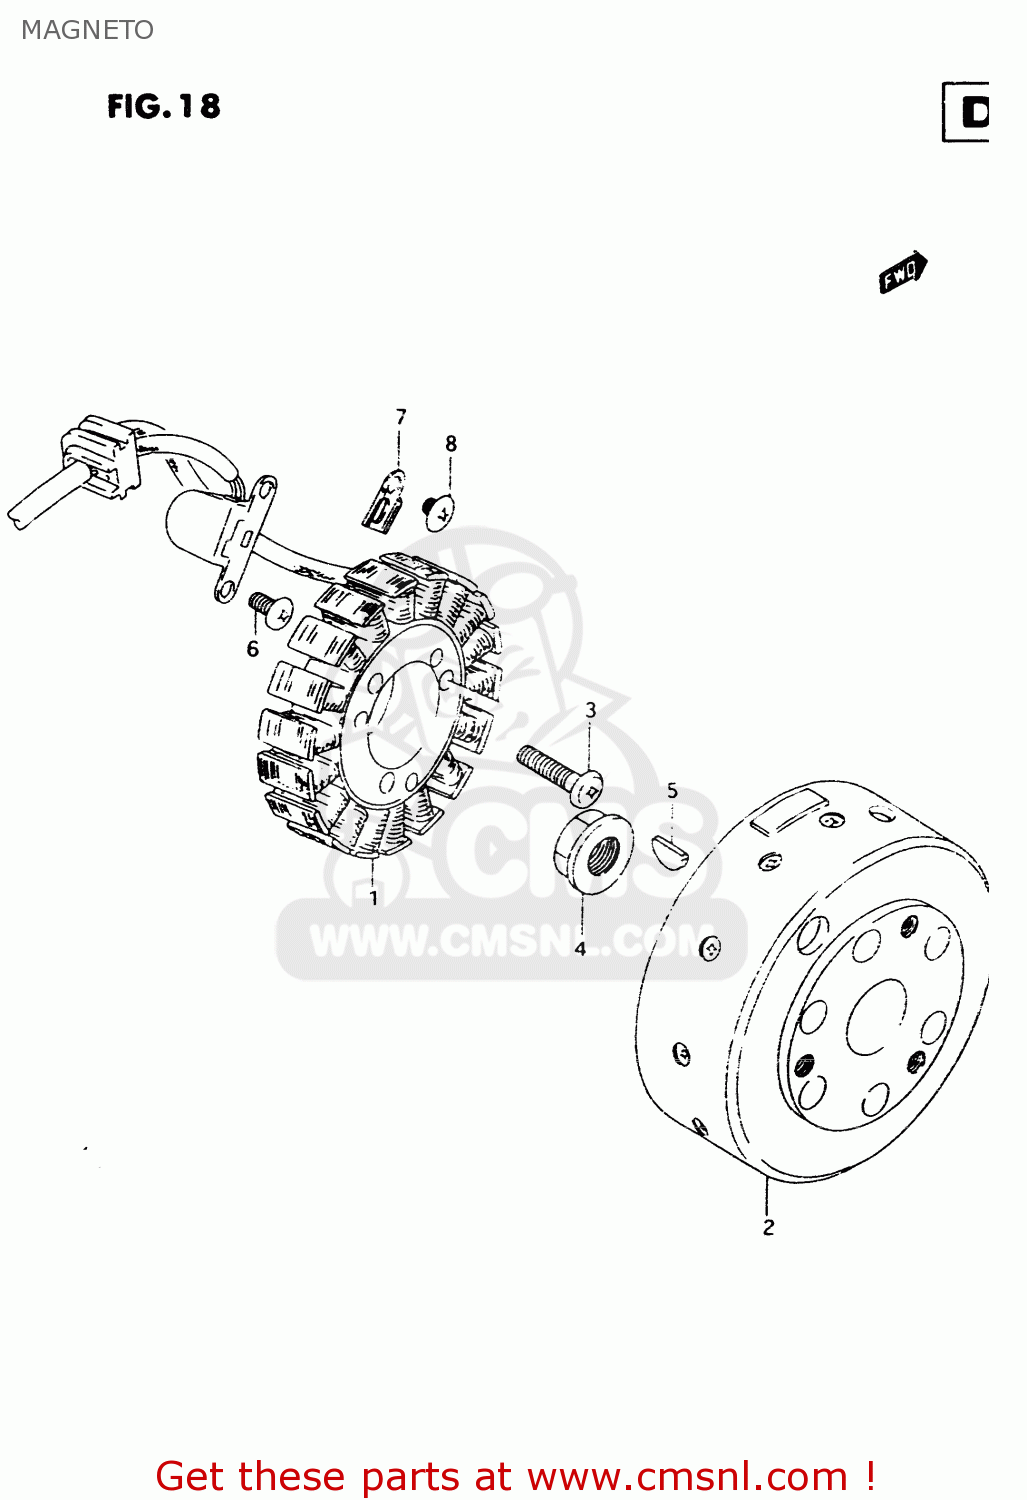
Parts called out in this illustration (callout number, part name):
1	STARTER ASSY
2	ROTOR
3	SCREW
4	NUT,GENERATOR ROTOR
5	KEY
6	SCREW
7	CLAMP, GENERATOR LEAD WIRE
8	SCREW
